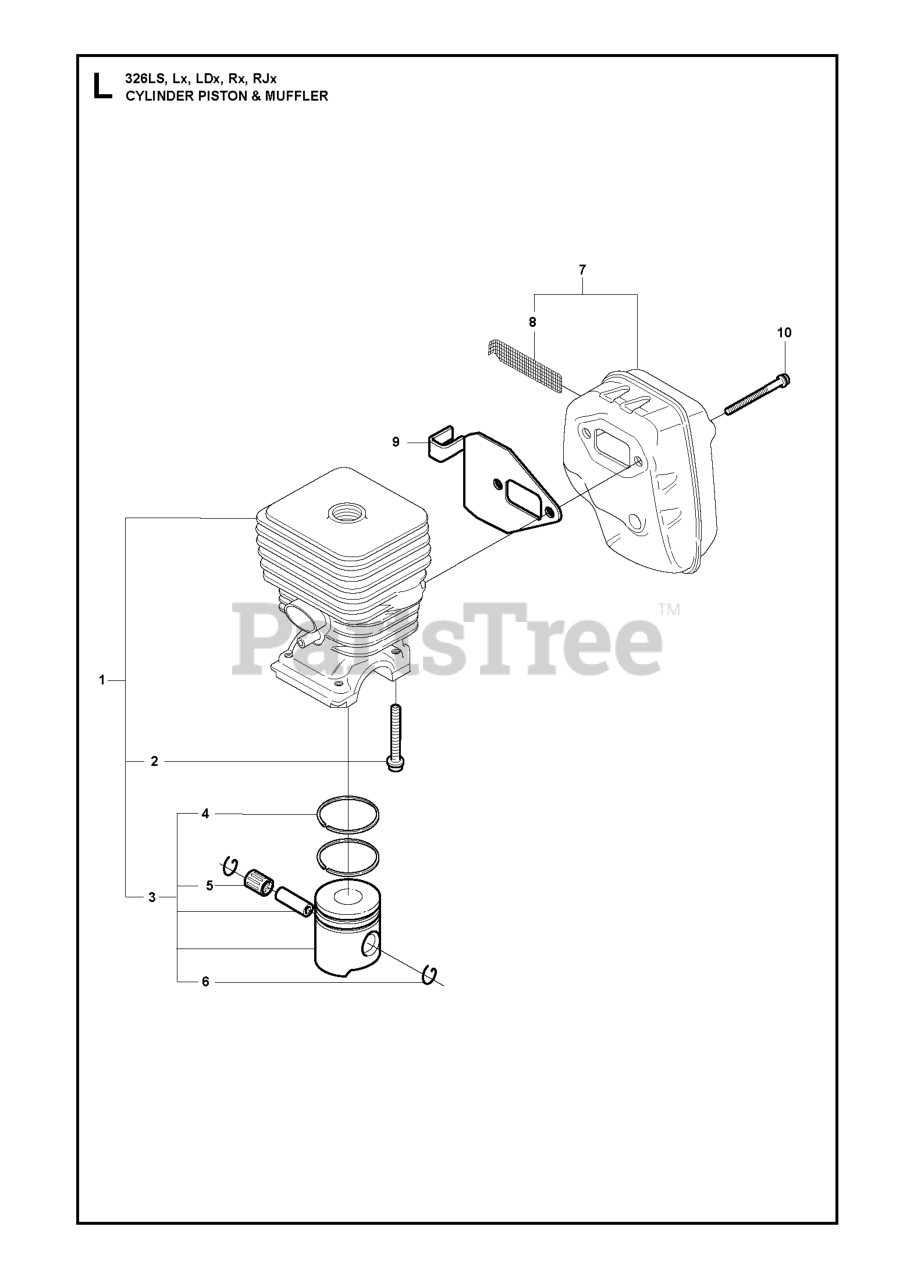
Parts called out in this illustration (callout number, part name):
1	CYLINDER
2	SCREW
4	PISTON RING
7	MUFFLER
8	SPARK ARRESTOR SCREEN
